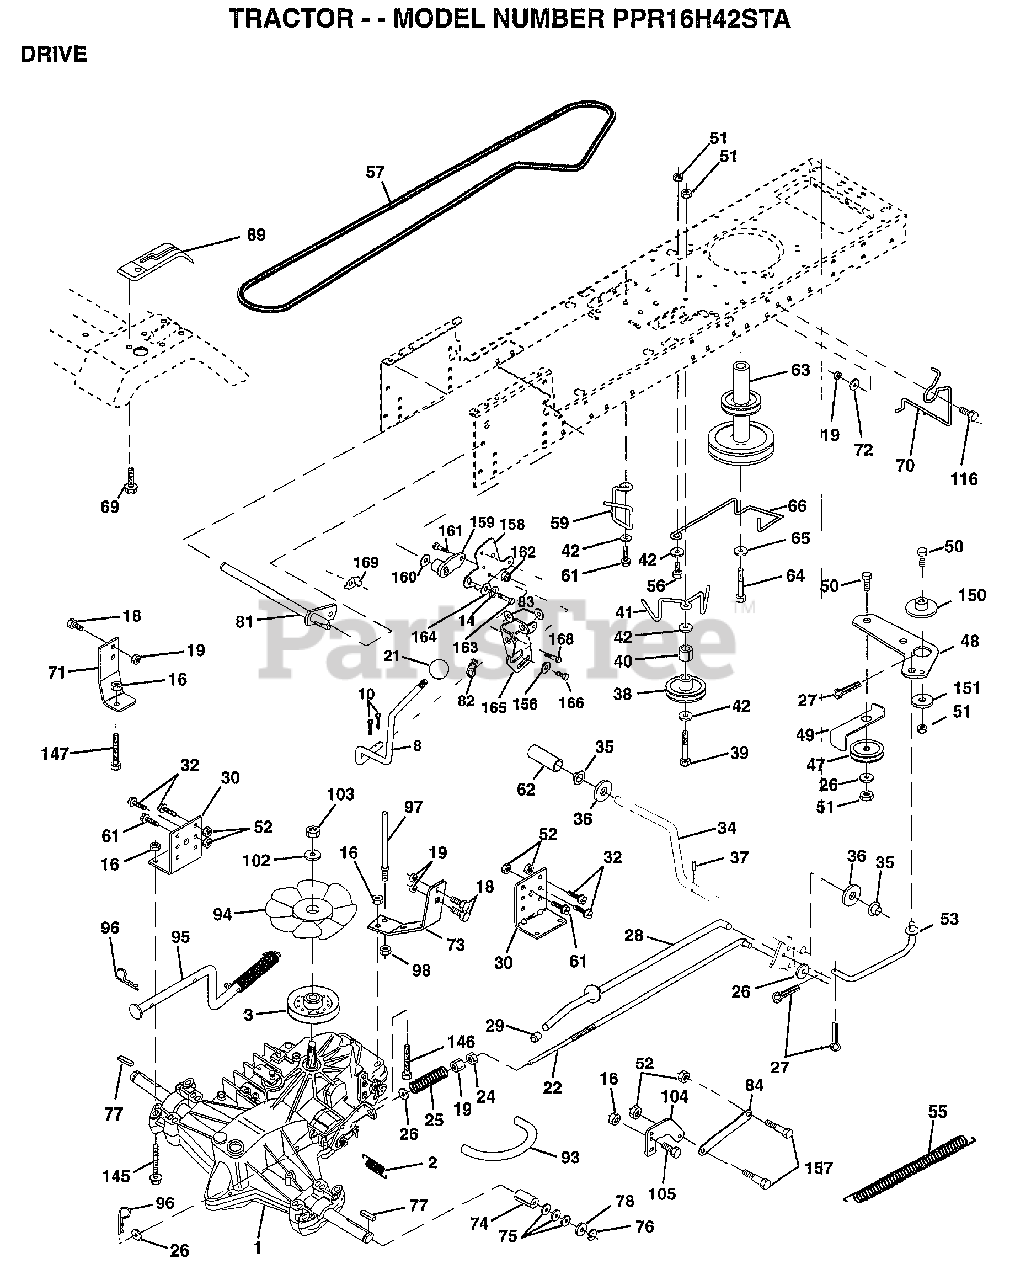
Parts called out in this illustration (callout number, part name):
2	SPRING RET BRAKE
3	PULLEY.TRANSAXLE
8	ROD.SHIFT.FENDER.ADJ.LT.CRD
10	PIN COTTER 1/8
14	LOCKWASHER
16	NUT
18	BOLT
19	NUT
21	KNOB DLX BLK/BLK
22	ROD.BRAKE.HYDRO.
24	NUT
25	SPRING ROD LT
26	WASHER
27	COTTER PIN
28	ROD.BRAKE.PARK.LT
29	PLUNGER CAP T
30	TRANSAXLE MTG BKT
32	BOLT
34	SHAFT ASM-PEDAL F
35	NYLON BEARING
36	WASHER LT
38	FLAT IDLER PULLEY
39	BOLT
40	SPACER T
41	"KEEPER,BELT.IDLER FLAT"
42	WASHER
48	BELLCRANK.CLUTCH
49	RETAIN BELT
53	"LINK, CLUTCH T"
55	"SPRING, RETURN LT"
57	"BELT.GD DRV 82"""
59	KEEPER BELT CNTSP
61	SCREW
62	PEDAL COVER T
63	PULLEY.ENGINE
64	BOLT
65	LOCKWASHER
66	KEEPER-BELT
69	SCREW HEXWSH H-L
70	KEEPER BELT ENG
71	STRAP TORQ LH HYD
72	WASHER
73	"STRAP-TORQUE,RH"
74	SPACER SPLIT
75	WASHER
76	E-RING LT
77	SQUARE KEY
78	WASHER
81	SHAFT.ASM.CROSS
82	"SPRING,TORSION"
83	WASHER
84	LINK.TRANSAXLE.LT/YT
89	CONSOLE.SHIFT.LT
93	"LINE FUEL HYD 4"""
94	"FAN 7"" HYDRO"
95	CONTROL.ASM.BYPASS.HYDRO.99
96	RETAINER M
97	BOLT KEEPER RH
98	NUT
102	WASHER BELLEVILLE
104	ARM CONTROL HYDRO
105	SCREW CAP 5/16-18
116	BOLT RDHD 3/8-16
145	BOLT.HEX.FLGHD
146	BOLT.HEX.FLGHD.
147	BOLT.HEX.FLGHD
150	BUSHING.BELLCRANK.GRD.DR
151	WASHER
156	WASHER.SRRTD.5/16
157	"BOLT,SHOULDER"
158	BRKT.SHIFT.MOUNT
159	HUB.SHIFT
160	WASHER
161	BOLT T
164	WASHER.5/8X.281X10GA
165	BRKT.PIVOT.LEVER
166	SCREW.5/16-18X5/8
168	BOLT.SHOULDER.5/16-18X.561
169	PLATE.FASTENING
